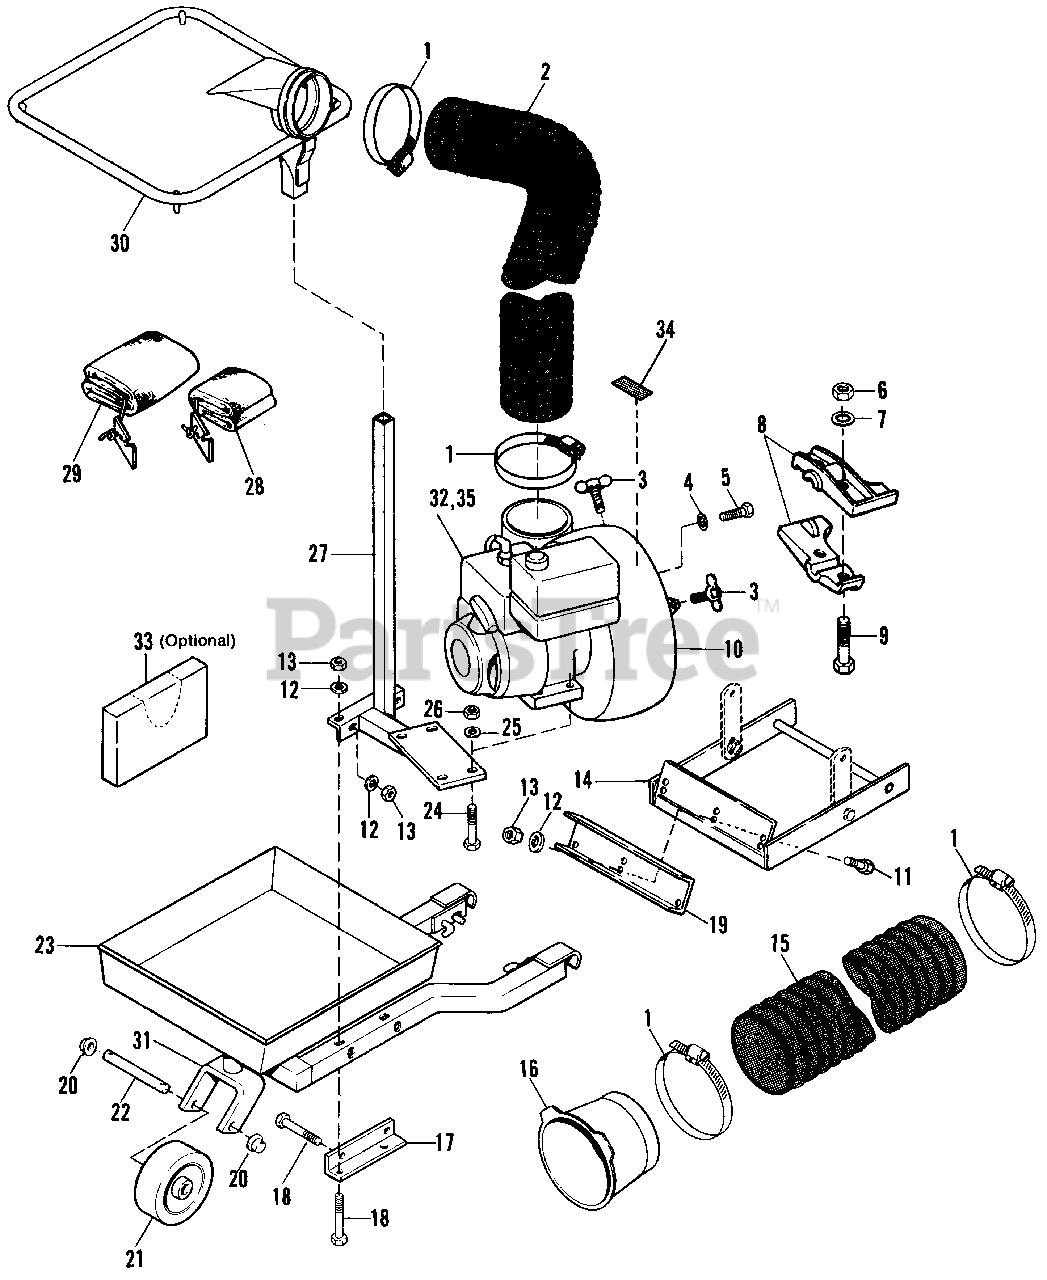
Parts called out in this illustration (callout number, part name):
1	CLAMP, Hose
2	HOSE, Flexible
3	BOLT, Wing, 5/16-18 x 2
4	LOCKWASHER, Int. Tooth, 5/16
5	CAPSCREW, Hex Hd. 5/16-24 x 3/4
6	NUT, Hex, Full, 1/2-13
7	LOCKWASHER, Int. Tooth, 1/2
8	BLADES, Blower (Pair)
9	CAPSCREW, Hex Hd., 1/2-13 x 1-1/2
10	HOUSING, Blower
11	LOCKWASHER, 3/8
12	WASHER, Plain, 3/8
13	NUT, Hex, Full, 3/8-16
14	HITCH ASSY.
15	HOSE, Lower
17	ANGLE, Reinforcing
18	CAPSCREW, Hex Hd., 3/8-16 x 2-1/2
19	CLAMP, Mount
21	WHEEL, Caster
22	AXLE, Caster
23	TRAY & SUPPORT ASSY.
24	CAPSCREW, Hex Hd. 5/16-18 x 1-1/2
25	LOCKWASHER, 5/16
26	NUT, Hex, Full, 5/16-18
27	ENGINE MOUNT & UPRIGHT
28	TOP, Canvas Bag
29	BAG, Canvas
30	RING, Bag Support
31	FORK ASSY., Caster
32	ENGINE, 4 H.P., Briggs & Stratton
33	LINERS, Plastic Bag (Pkg. of 18)
34	DECAL, Warning
35	MUFFLER
